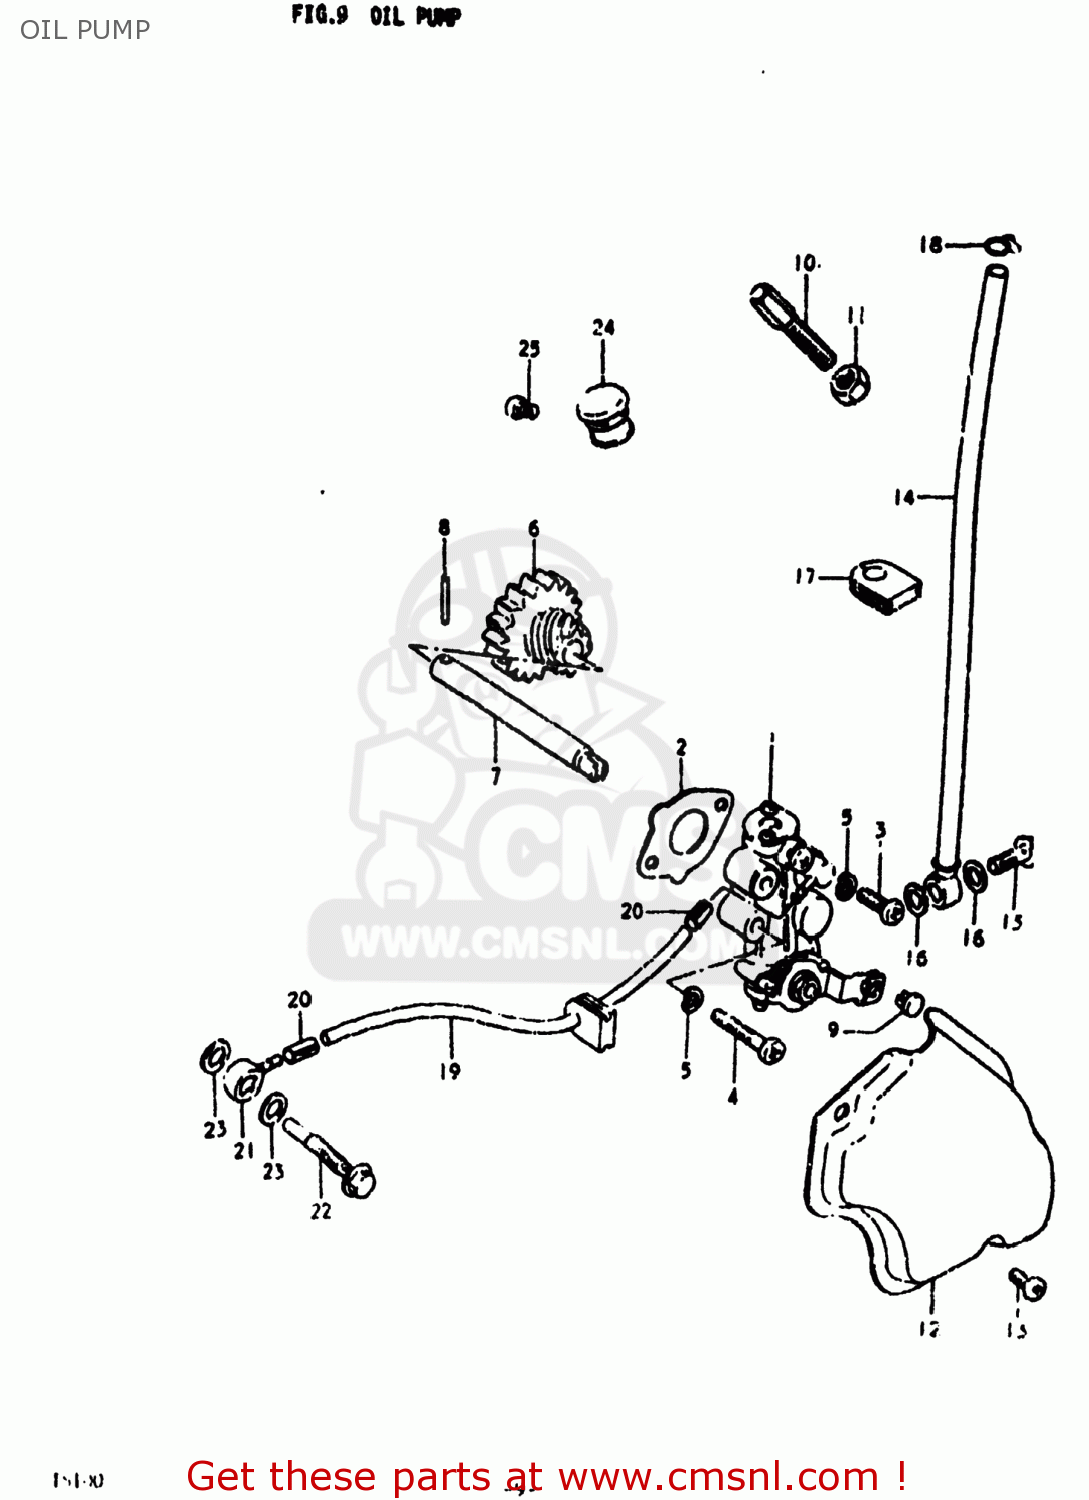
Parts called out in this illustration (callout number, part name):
1	PUMP ASSEMBLY,OIL
2	GASKET,OIL PUMP (MCA)
3	SCREW
4	SCREW
5	LOCK WASHER
6	GEAR,OIL PUMP DRIVE
7	SHAFT,OIL PUMP DRIVE
8	PIN(2.5X19.8)
9	TERMINAL,CABLE
10	BOLT
11	NUT
12	CAP,OIL PUMP INSPECTION
13	SCREW
14	HOSE,OIL NO.1
15	UNION BOLT
16	GASKET(6.2X11X1).2 (NAS)
17	GROMMET
18	CLIP
19	HOSE,OIL NO.2
20	CLIP
21	UNION
22	UNION
23	GASKET(6.2X11X1).2 (NAS)
24	Plug
